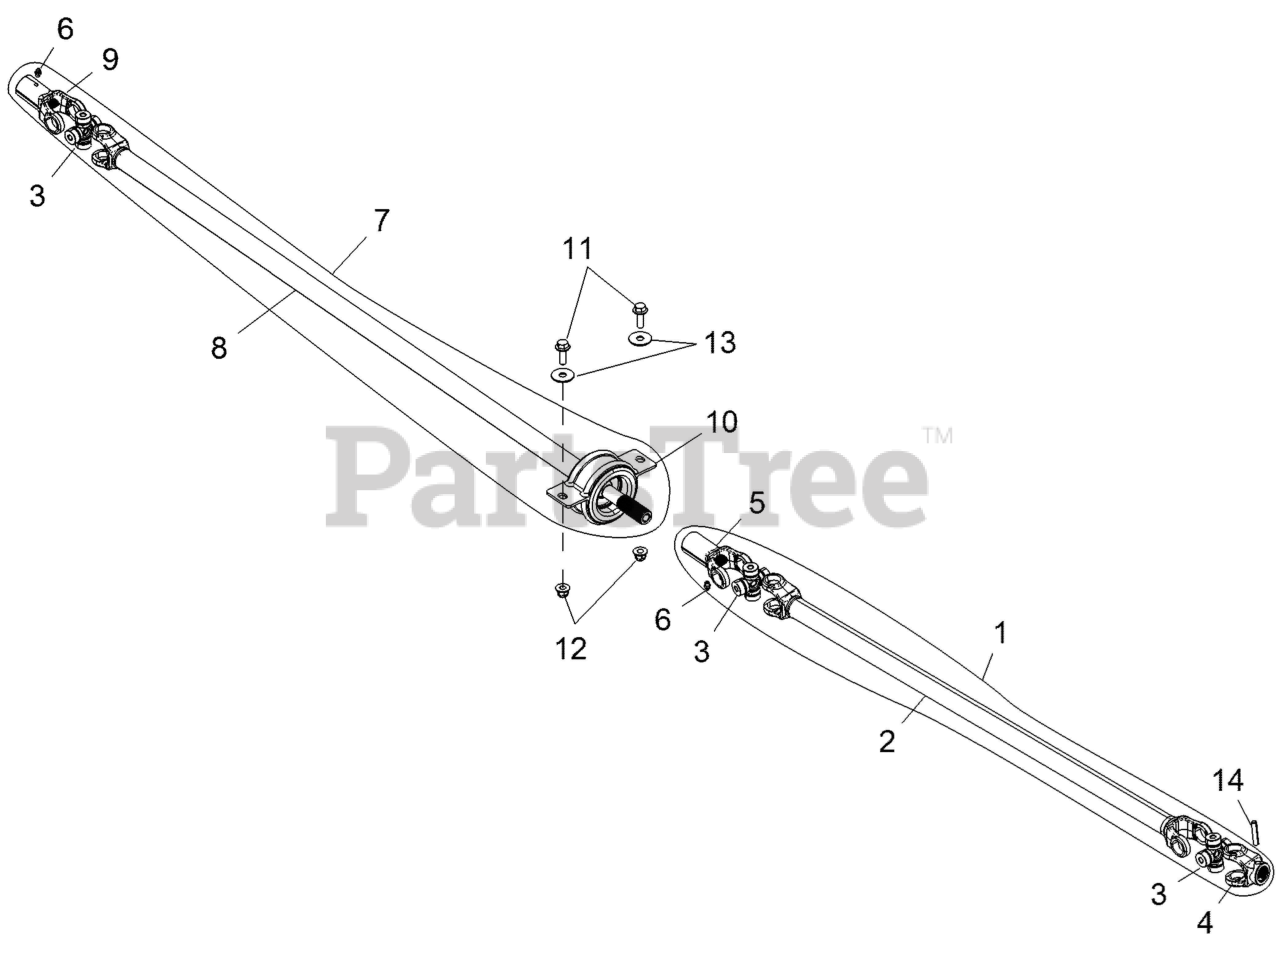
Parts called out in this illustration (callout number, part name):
1	ASM-PROPSHAFT,FRONT
2	WELD-PROPSHAFT,FRONT
3	U-JOINT-1000 SERIES
4	YOKE-PIN
5	YOKE, SLIP, INDEXED
6	FITTING, LUBRICATION
7	ASM-PROPSHAFT,REAR
8	WELD-PROPSHAFT,REAR
9	YOKE-SLIP
10	ASM, FLEX BEARING
11	SCR-HXFL-M10X1.25X30 8.8 ZOD
12	NUT-M10X1.25,FLG,NYLOC-OLIVE D
13	WASHER, FLAT
14	PIN,SPRING(10)
